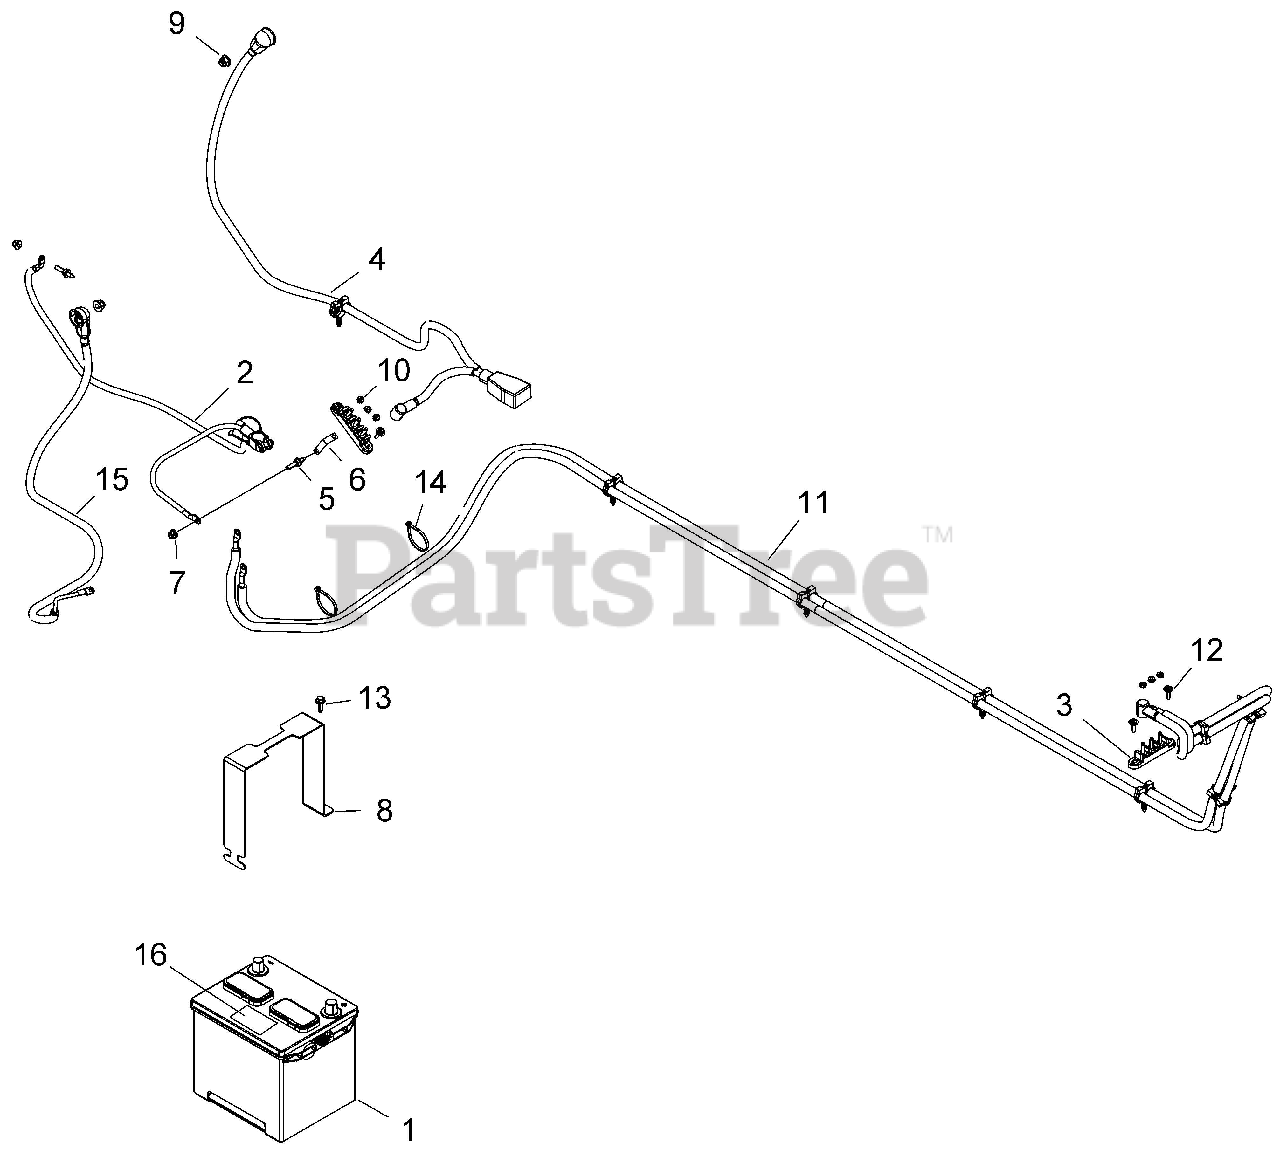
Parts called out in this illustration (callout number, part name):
1	BATTERY-575 CCA,FLOODED,FILLED
2	ASM., CABLE, BAT TO GROUND/TERM
3	BLOCK-TERMINAL,3 POST
4	CABLE, BATTERY TO ALT.
5	STUD-M6X1.0X19-M6 TAPTITE
6	STRAP-GROUND
7	NUT-M6 FLANGE,NYLOK
8	BRKT-BATTERY STRAP GALV
9	NUT-M8X1.25,HXFLG,NYLON INS
10	NUTS-10-32 KEPS
11	CABLE, TERMINAL BLOCK
12	SCR-10-24X3/4 PH/TX/TRI-SEMS Y
13	SCR-M6X1.0X20,HXHD,FLG,TDFM,BL
14	CABLE TIE (10)
15	CABLE, ALTERNATOR, BATTERY
16	DECAL, BATTERY
